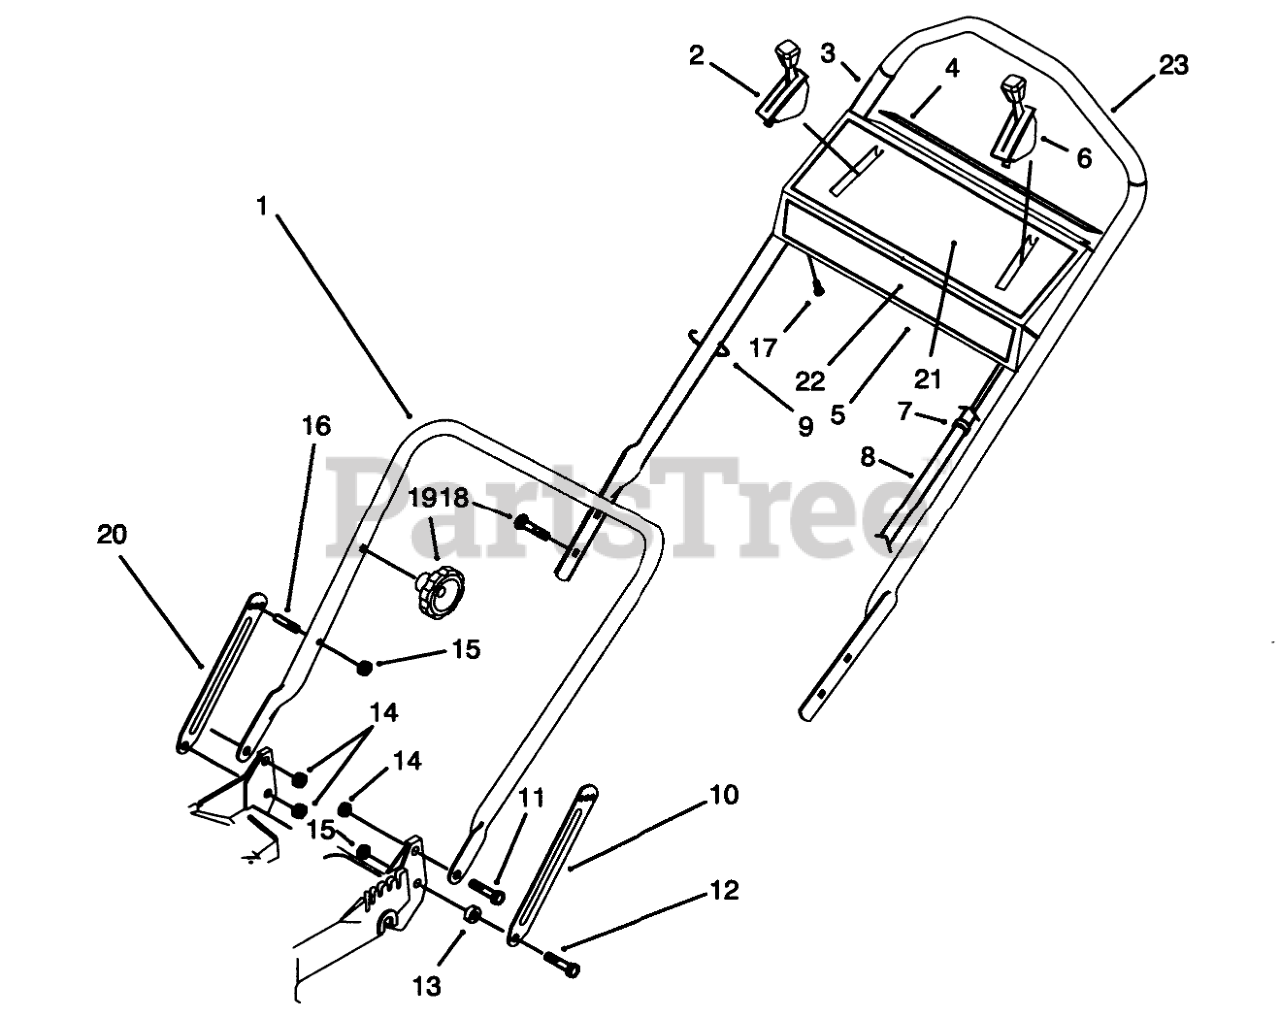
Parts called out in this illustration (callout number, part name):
1	LOWER HANDLE ASM
2	CONTROL-SPEED, GROUND
3	Handle-Upper
4	DECAL - PANEL, REAR
5	Panel-Control (Incl. Ref. #4, 21, & 22)
6	THROTTLE CONTROL
7	FITTING-RING
8	CONTROL CABLE COVER
9	TIE-CABLE
10	Latch-Handle
11	SCREW-SHOULDER
12	SCREW-SHOULDER
13	SPACER
14	NUT-LOCK, NI
15	NUT-LOCK, NI
16	HANDLE PIN
17	10-16X1/2 SHWH SCREW
18	SCREW-HANDLE
20	Latch-Handle
21	DECAL - INSTRUCTION
22	DECAL - FRT PANEL
23	Grip-Foam
